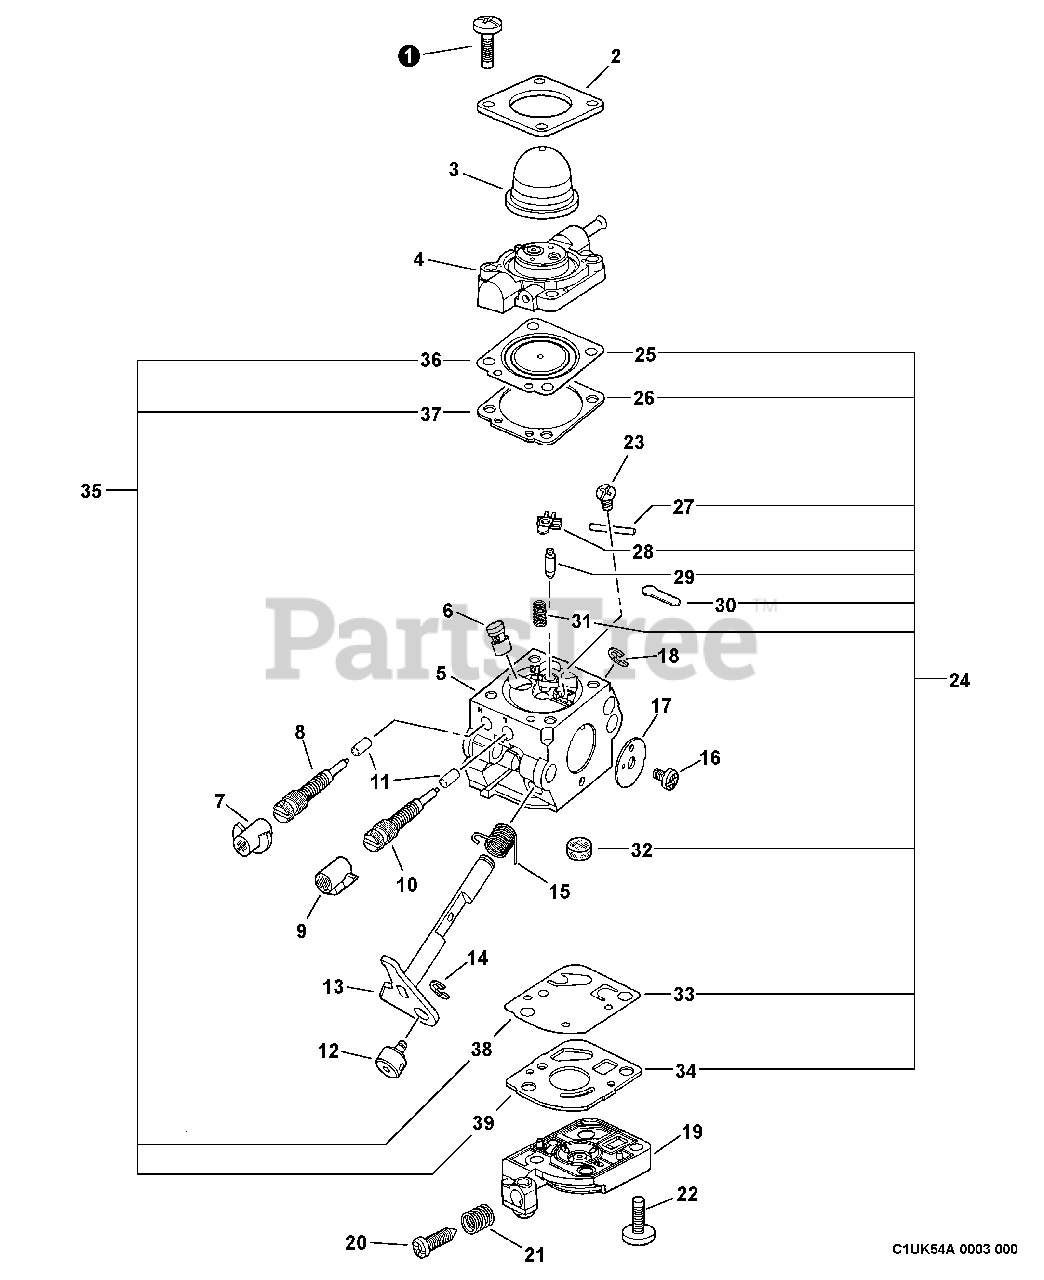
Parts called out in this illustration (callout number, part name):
1	SCREW, RETAINER
2	RETAINER, PURGE BULB
3	BULB, PURGE
4	BASE, PURGE
5	BODY, CARBURETOR
6	NOZZLE, CHECK VALVE
7	CAP, LIMITER
8	NEEDLE - HIGH SPEED
9	CAP, LIMITER
10	NEEDLE - LOW SPEED
11	RETAINER
13	SHAFT, THROTTLE
14	RING, RETAINING
15	SPRING, RETURN
17	VALVE, THROTTLE
18	RING, RETAINING
19	BASE, PURGE
20	SCREW, IDLE ADJUST
21	SPRING, IDLE ADJUST
22	SCREW, PUMP COVER
23	SCREW, METERING LEVER PIN
24	REPAIR KIT
25	DIAPHRAGM, METERING
26	GASKET, METERING
27	PIN, METERING LEVER
28	LEVER, METERING
29	VALVE, INLET NEEDLE
30	PLUG, WELCH
31	SPRING, METERING LEVER
32	STRAINER
33	DIAPHRAGM, PUMP
34	GASKET, PUMP
35	DIAPHRAGM/GASKET KIT
36	DIAPHRAGM, METERING
37	GASKET, METERING
38	DIAPHRAGM, PUMP
39	GASKET, PUMP
